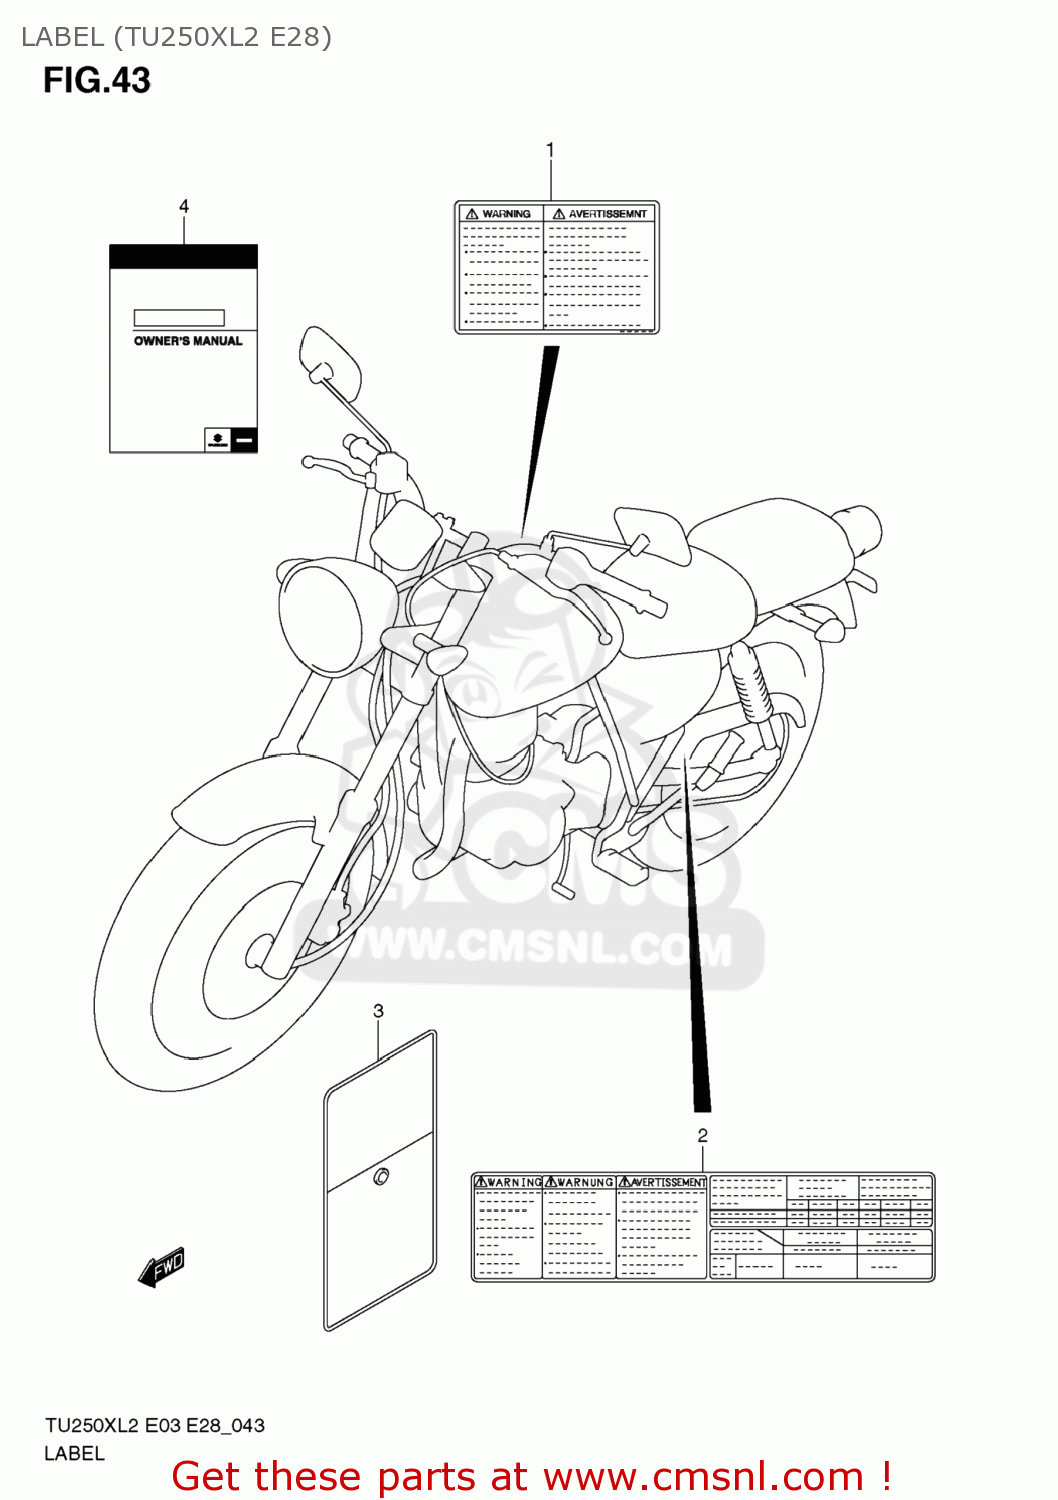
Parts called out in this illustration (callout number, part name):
1	LABEL,GENERAL WARNING
2	LABEL,TIRE INFORMATION
3	BAG,OWNER'S MANUAL
4	MANUAL,OWNER'S
